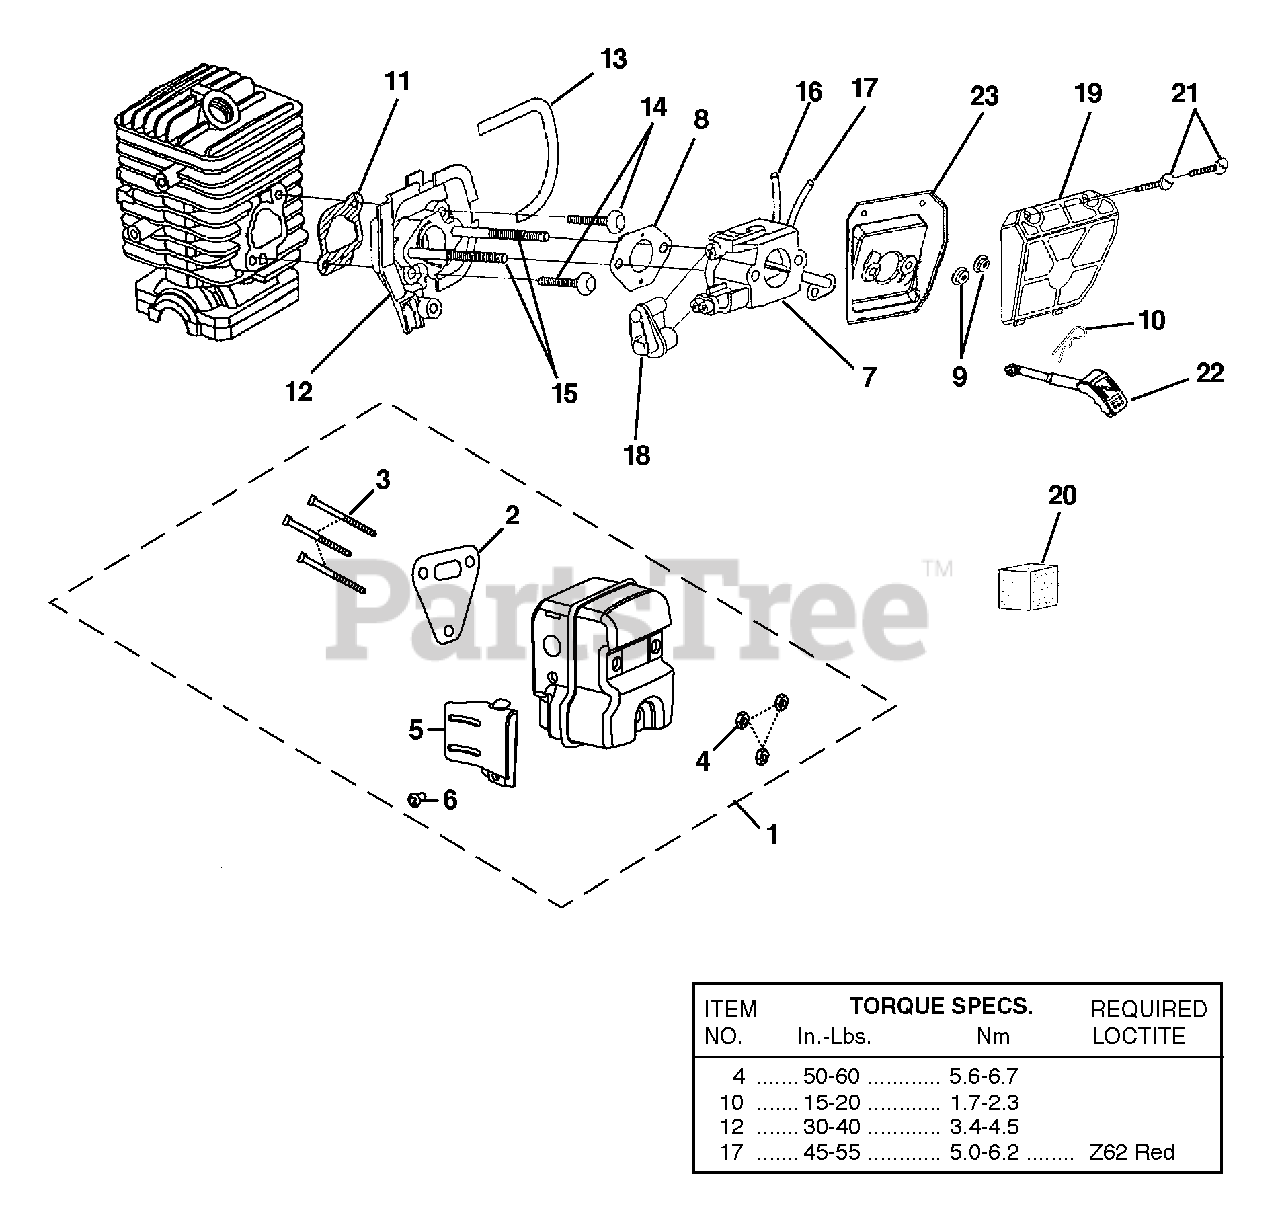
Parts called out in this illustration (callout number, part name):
1	Muffler Kit
2	Muffler Gasket
3	Screw-Square Hd.
4	Nut-Locking Hex (10-32)
5	Deflector, Muffler
6	Screw (8-32 X .312 Pan Hd.)
7	Carburetor Assembly
8	Carburetor Gasket
9	Flange Nut (10-24)
10	Spring Clip (Choke Rod)
11	Gasket, Heat Dam
12	Carburetor Spacer
13	Seal, Heat Dam
14	Screw, Truss Hd.Taptite (10-24 x 7/8")
15	Screw, Carburetor
16	Fuel Line (Tank to Carburetor 81/2")
17	Fuel Line (Carburetor to Purge Bulb 2")
18	Carburetor Grommet
19	Air Filter Cover
20	Pre Filter (In engine housing)
21	Screw-Slotted Pan Hd. (8-16 x 5/8")
22	Rod, Choke
23	Air Filter Plate
